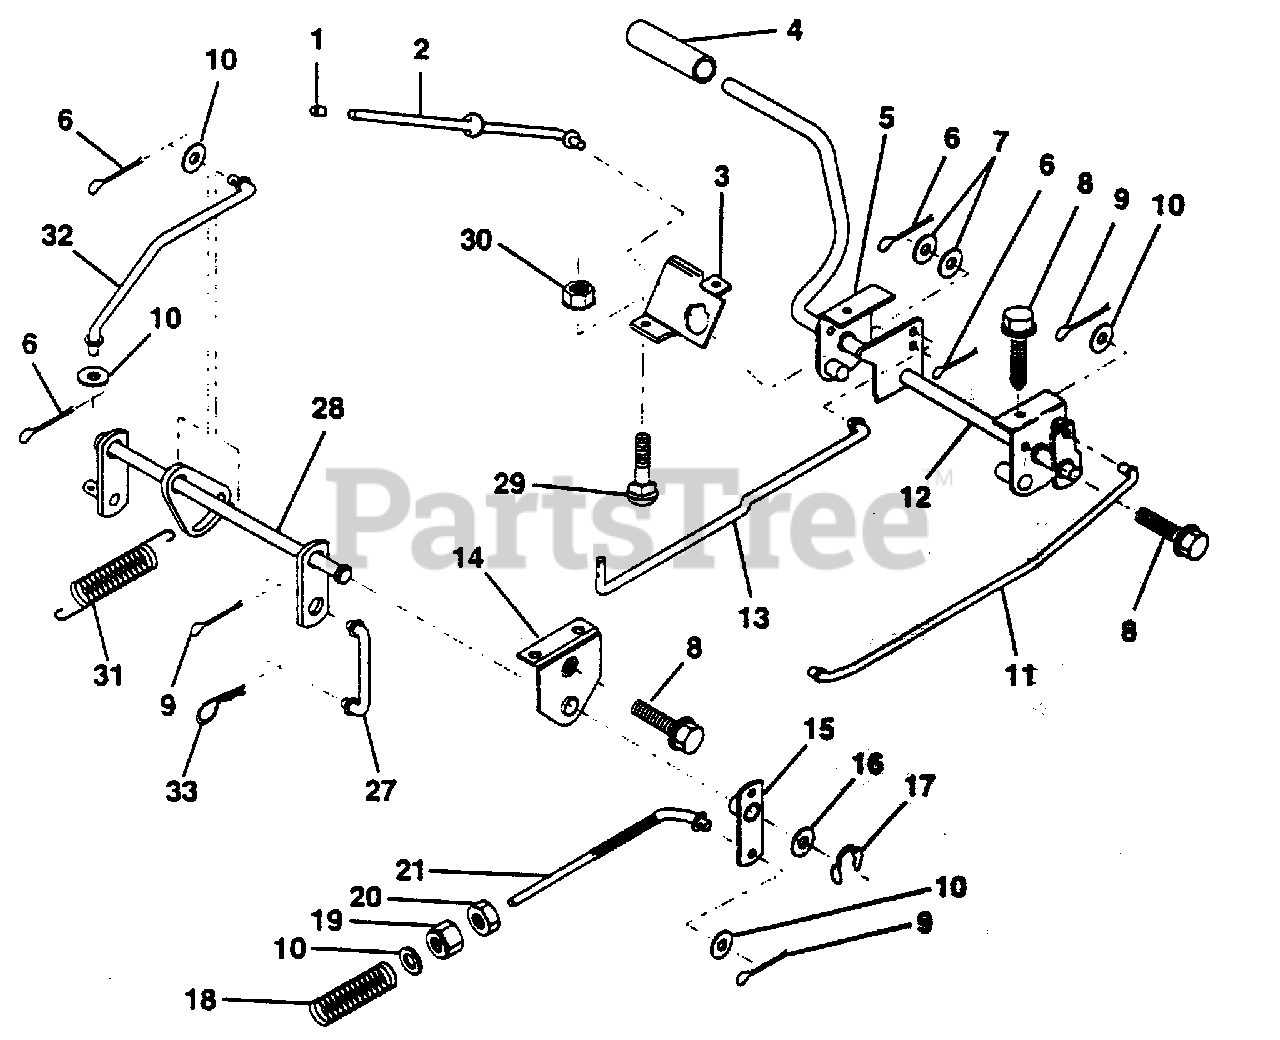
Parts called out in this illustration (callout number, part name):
1	Cap, Plunger (AYP part number)
2	Rod, Parking Brake (AYP part number)
3	Bracket, Parking Brake (AYP part number)
4	Cover, Pedal (AYP part number)
5	Bracket, Clutch/Brake Pedal, L.H. (AYP part number)
6	Pin, Cotter 3/32 x 3/4 (AYP part number)
7	Washer 13/32 x 5/8 x 16 Gauge (AYP part number)
8	Screw, Hex Head, Thd., Roll. 5/16-18 x 1/2 (AYP part number)
9	Pin, Cotter 1/8 x 3/4 (AYP part number)
10	Washer 13/32 x 13/16 x 16 Gauge (AYP part number)
11	Rod, Brake, Front (AYP part number)
12	Assembly, Clutch/Brake Pedal (AYP part number)
13	Rod, Clutch (AYP part number)
14	Bracket, Lift Shaft (AYP part number)
15	Assembly, Brake, Pivot, Arm (AYP part number)
16	Washer 25/32 x 1-1/8 x 16 Gauge (AYP part number)
17	Ring, Klip (AYP part number)
18	Spring, Brake Rod (AYP part number)
19	Locknut, Hex, w/Wsh Ins 3/8-16 UNC (AYP part number)
20	Nut, Hex, Jam 3/8-16 UNC (AYP part number)
21	Rod, Brake, Rear
27	Link, Lift, Rear (AYP part number)
28	Assembly, Rear Mower Lift (AYP part number)
29	Bolt, Carriage 5/16-18 UNC x 3/4 (AYP part number)
30	Nut, Hex, Keps 5/16-16 UNC (AYP part number)
31	Spring, Counterbalance (AYP part number)
32	Link, Lift Lever (AYP part number)
33	Retainer Spring (AYP part number)
